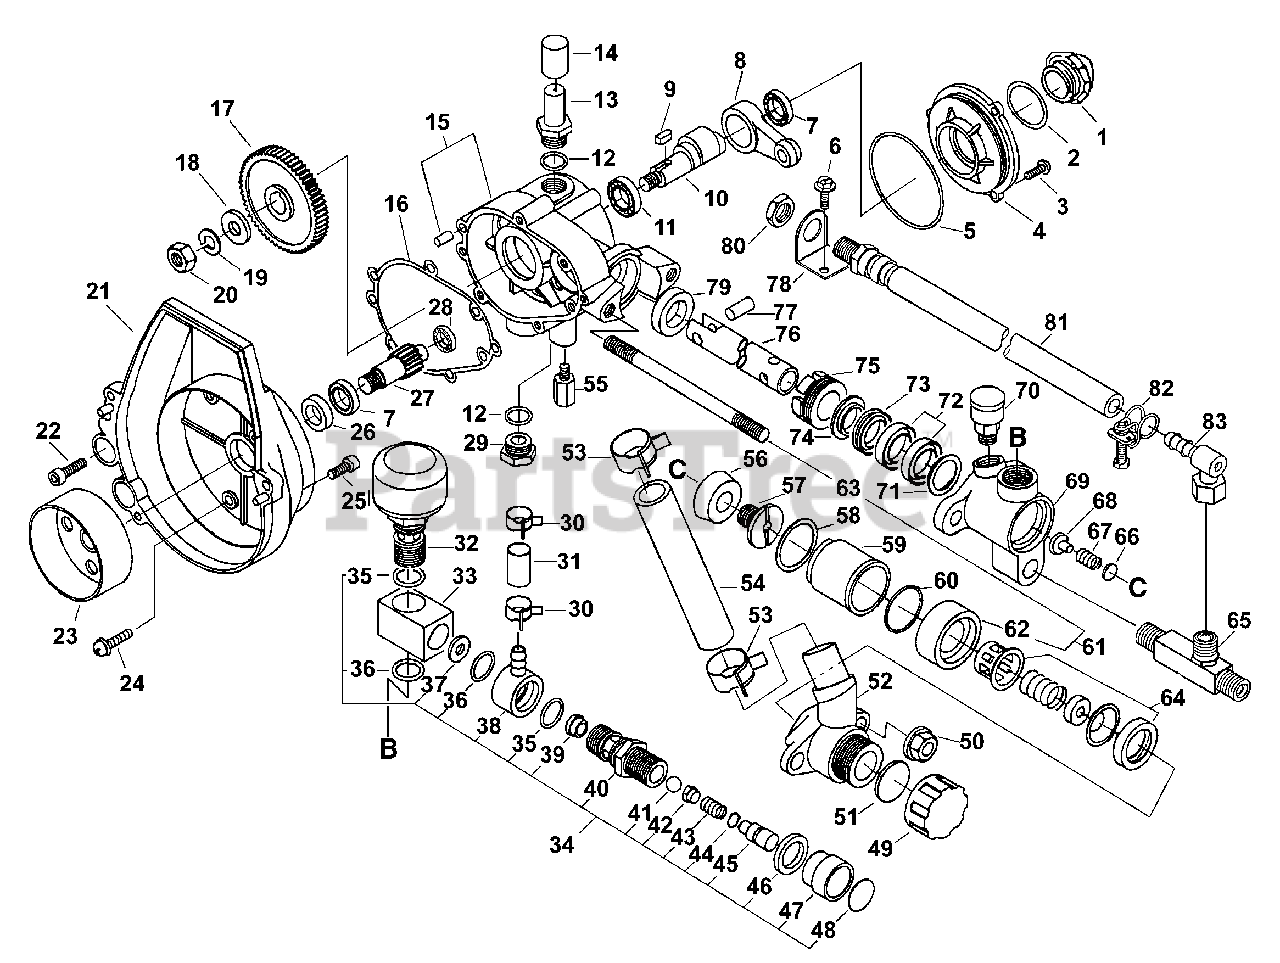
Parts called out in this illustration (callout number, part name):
1	GAUGE, OIL
3	SCREW 4×12
4	COVER, PUMP
6	SCREW 5×14
7	BEARING, BALL 6001
8	ROD, CONNECTING
10	CRANKSHAFT
11	BEARING, BALL 6201
13	BOLT, OIL
15	CASE KIT, PUMP
17	GEAR, SPUR
18	WASHER 8.5×16×1.2
19	WASHER, SPRING 8
21	COVER, FAN
22	BOLT 5×25
23	DRUM, CLUTCH
24	SCREW 5×25
25	BOLT 5×18
26	SEAL, OIL
27	SHAFT, PINION
28	BEARING, BALL 609
29	CAP, DRAIN
30	CLIP 10.5MM
31	HOSE, RETURN
32	CHAMBER, AIR
33	CONNECTOR
34	REGULATOR ASSY
35	O-RING 12.5
36	O-RING 16 MM
38	CASING, VALVE
39	SEAT, VALVE
40	CASING, SPRING
41	BALL, PRESSURE STEEL
42	HOLDER, SPRING
43	SPRING, PRESSURE
44	O-RING 7 MM
45	SHAFT, REGULATOR
47	CAP, REGULATOR
48	LABEL, REGULATOR
49	CAP, DRAIN
51	GASKET, DRAIN
52	PIPE, INTAKE
54	HOSE, INLET
56	PACKING, PISTON
57	SEAT, VALVE
61	VALVE, PLUNGER
62	CASING, VALVE
63	BOLT, STUD
64	VALVE ASSY, PLUNGER
65	CONNECTOR
67	PLATE, SPRING
68	HOLDER, SPRING
69	CYLINDER
70	CUP ASSY, GREASE
72	PACKING SET
73	PACKING, GREASE
76	PLUNGER SET, W/SPRING
77	PIN, PISTON
78	BRACKET, MOUNTING
79	SEAL, OIL
80	NUT
81	HOSE, SHORT
82	BAND, SPRING
83	JOINT, HOSE
